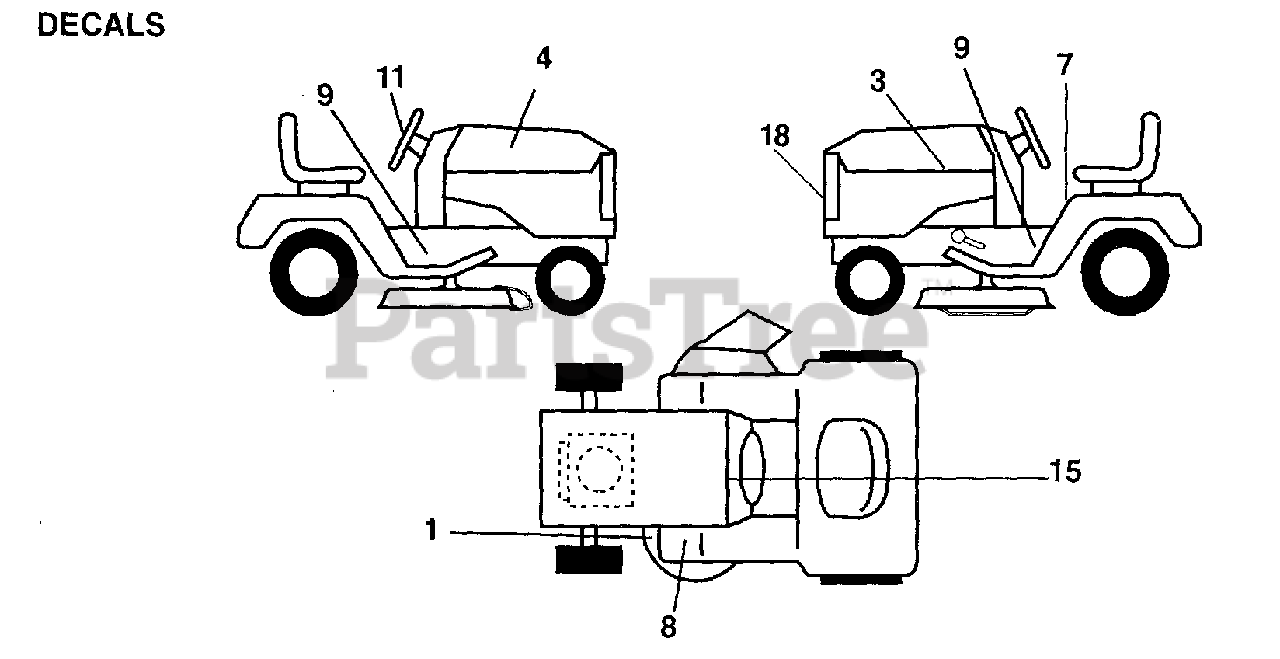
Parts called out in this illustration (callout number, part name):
1	DECAL
7	DECAL
15	DECAL.DASH.INST.
